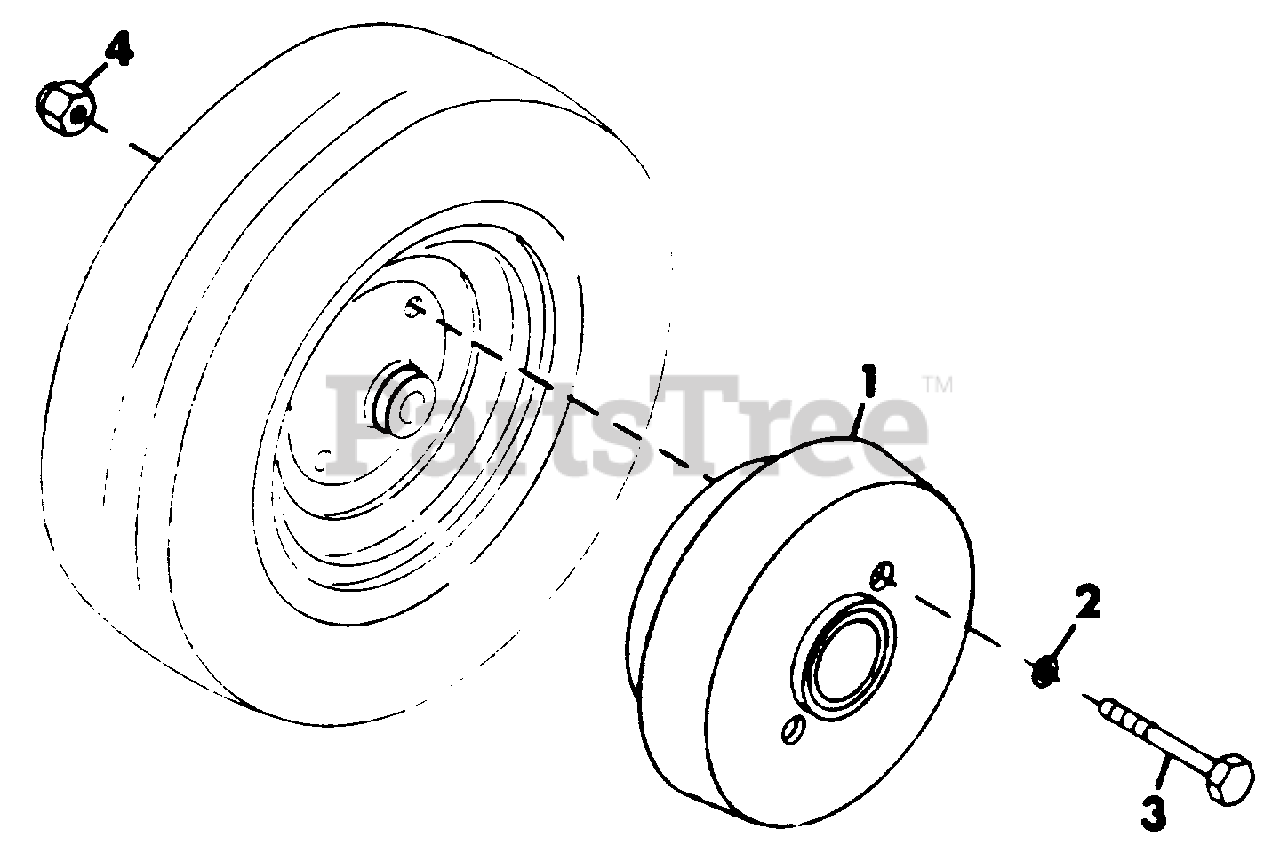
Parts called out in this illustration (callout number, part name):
1	WEIGHT, FRONT WHEEL
2	WASHER, FLAT .406X.812X.065
3	BOLT, HEX 3/8-16X6.00
4	NUT, LOCK 3/8-16
